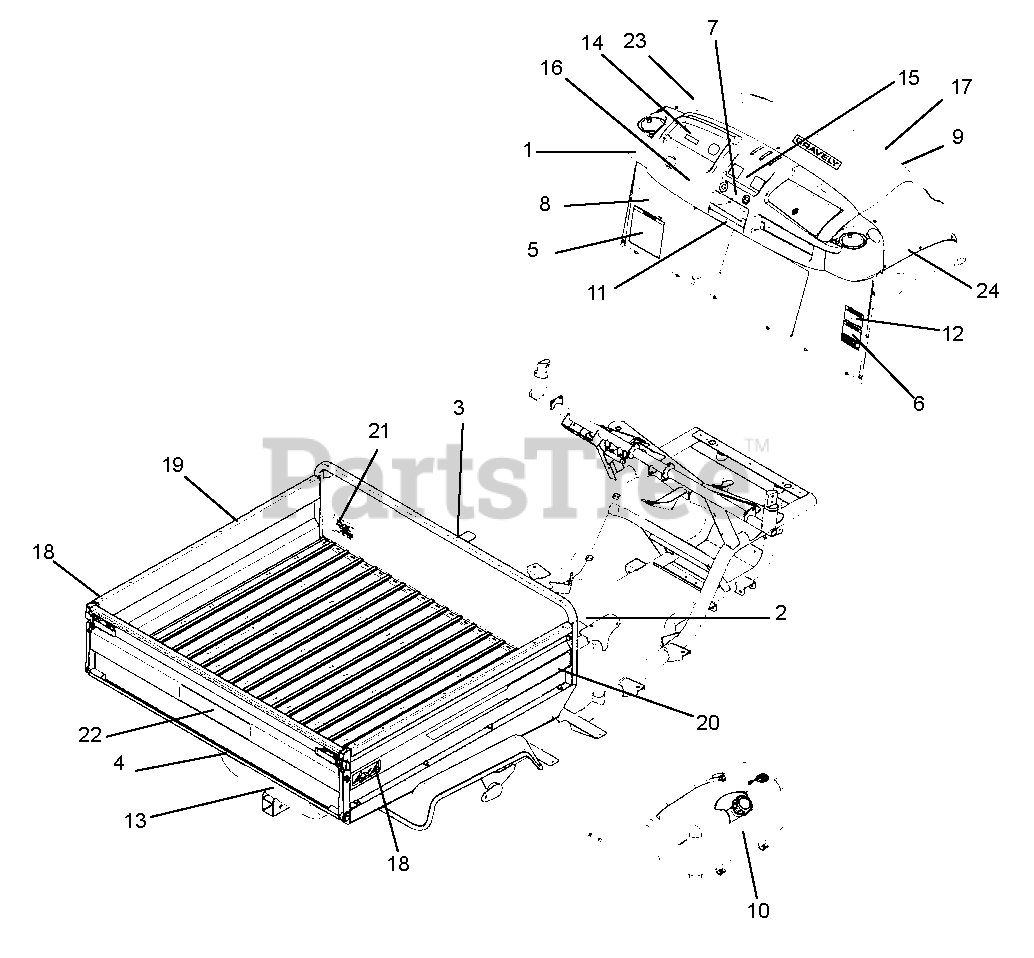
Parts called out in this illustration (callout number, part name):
1	DECAL, GRAVELY HERITAGE – SMALL
2	DECAL, DANGER PD GUARD MISS SML
3	DECAL, DANGER BATTERY
4	DECAL, DANGER HOT
5	DECAL, WARNING GNRAL UTLTY VHCL
6	DECAL, WARNING ROLLOVER HAZARD
7	DECAL, HAND BRAKE
8	DECAL, WARNING IMPROPER USE
9	DECAL, CAUTION PWR SRC MAX 12V
10	DECAL, WARNING ENG. COOL B4 GAS
11	DECAL, WARNING VEHICLE ROLLOVER
12	2WD PAYLOAD LABEL
13	LABEL, TRAILER TOWING 1,500LB
14	DECAL, START INSTRUCTION
15	DECAL, SWITCH PANEL
16	DECAL, SHIFT INSTRUCTION
17	DECAL, BATTERY DISCONNECT
18	DECAL, 4 X 4, RED (996146)
19	DECAL, BEDSIDE LEFT HAND SIDE (996123, 125, 146)
20	DECAL, BEDSIDE RIGHT HAND SIDE (996123, 125, 146)
21	DECAL, WARNING PINCH PT/CRUSH
22	DECAL, GRAVELY LOGO
23	DECAL, HOOD LEFT HAND
24	DECAL, HOOD RIGHT HAND
